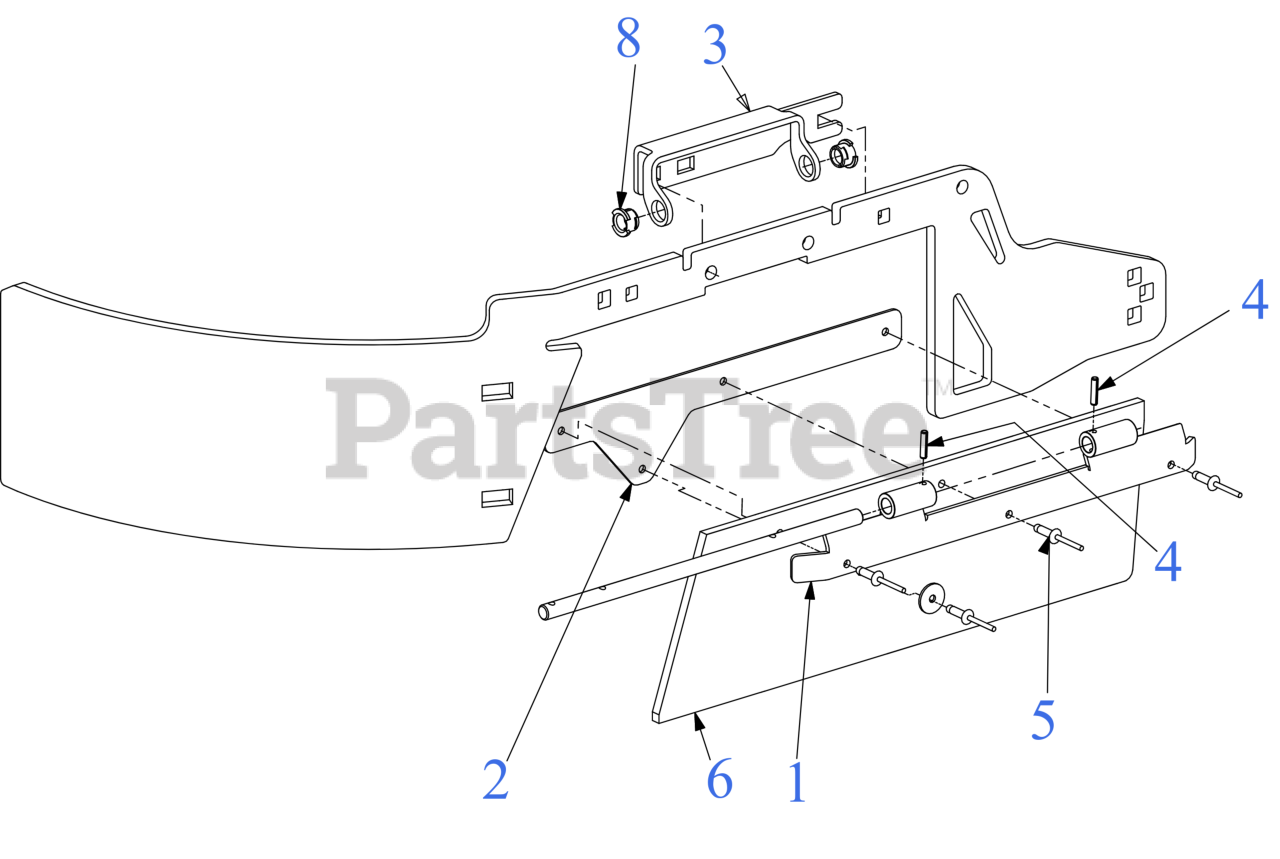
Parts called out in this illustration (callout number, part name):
1	DEFLECTING DOOR BRACKET
2	DECK DOOR SUPPORT PLATE
4	ROLL PIN 5/32" x .688"
5	POP RIVET .187 DIA
7	Flat Washer: 3/16 x 3/4 x 16G
8	BUSHING .380 ID
9	ROD:3/8":DOOR:CHUTE
